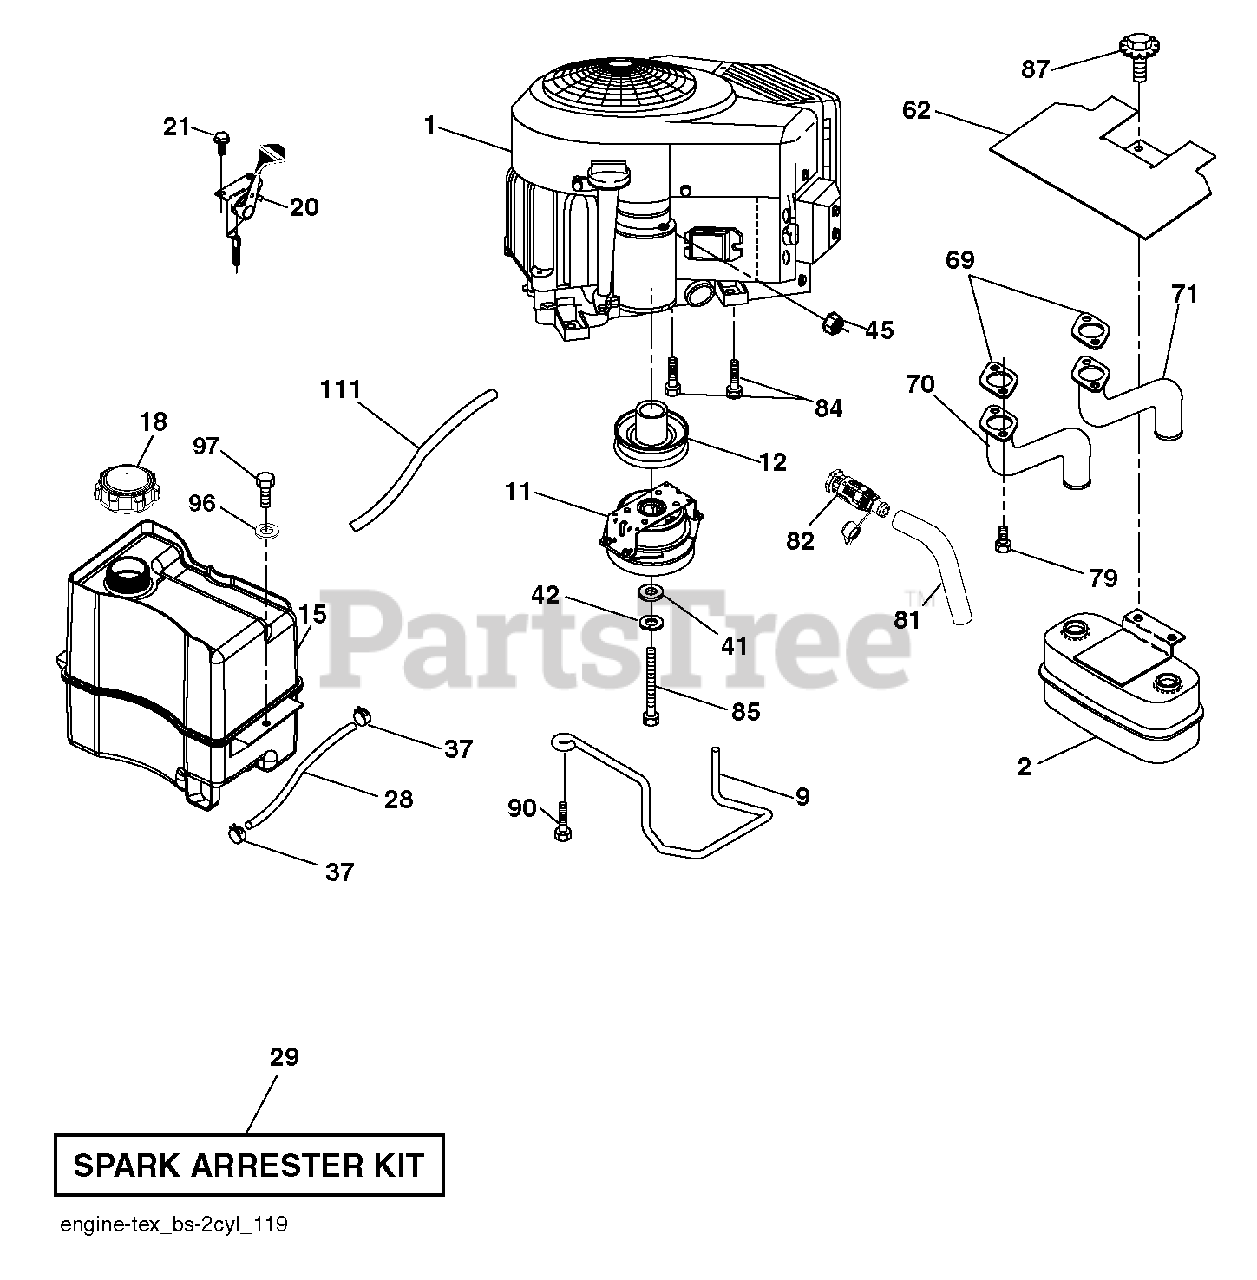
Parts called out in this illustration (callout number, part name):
2	MUFFLER.TWIN.CYL.LOW.TONE
9	KEEPER.BELT.ENGINE.3.25
11	Clutch, Ogura 5.0Pd Gt1.5A-Eh07
12	PULLEY.ENGINE.ENX
15	TANK.ASM.FRT.2.5 GAL.W/CAP.EPA
18	CAP.FUEL.2 WAY VENT
20	CONTROL.TH/CK.COBRA.B&S.TWN.
21	SCREW.#10 X 0.750.BOS (2 2)
28	LINE.FUEL.20
29	SPARK ARRESTOR KIT
37	HOSE CLAMP
42	LOCKWASHER
45	NUT
62	SHIELD.HEAT.MUFFLER
69	GASKET.MUFFLER
70	EXHAUST.TUBE.LH.BS/TWIN
71	EXHAUST.TUBE.RH.B&S.TWIN.INTEK
79	SCREW.SOCKET.HEAD.5/16-18
81	TUBE, DRAIN OIL ASM.
82	VALUE.OIL.DRAIN
84	SCREW.3/8-16
85	BOLT HEX 7/16-20 X 3.75 GR. 5
87	BOLT, 5/16-18 X 1 3/4
90	SCREW 3/8-16X1
97	SCREW HEXWSHR 1/4-20X3/4
111	RP PURGE LINE
